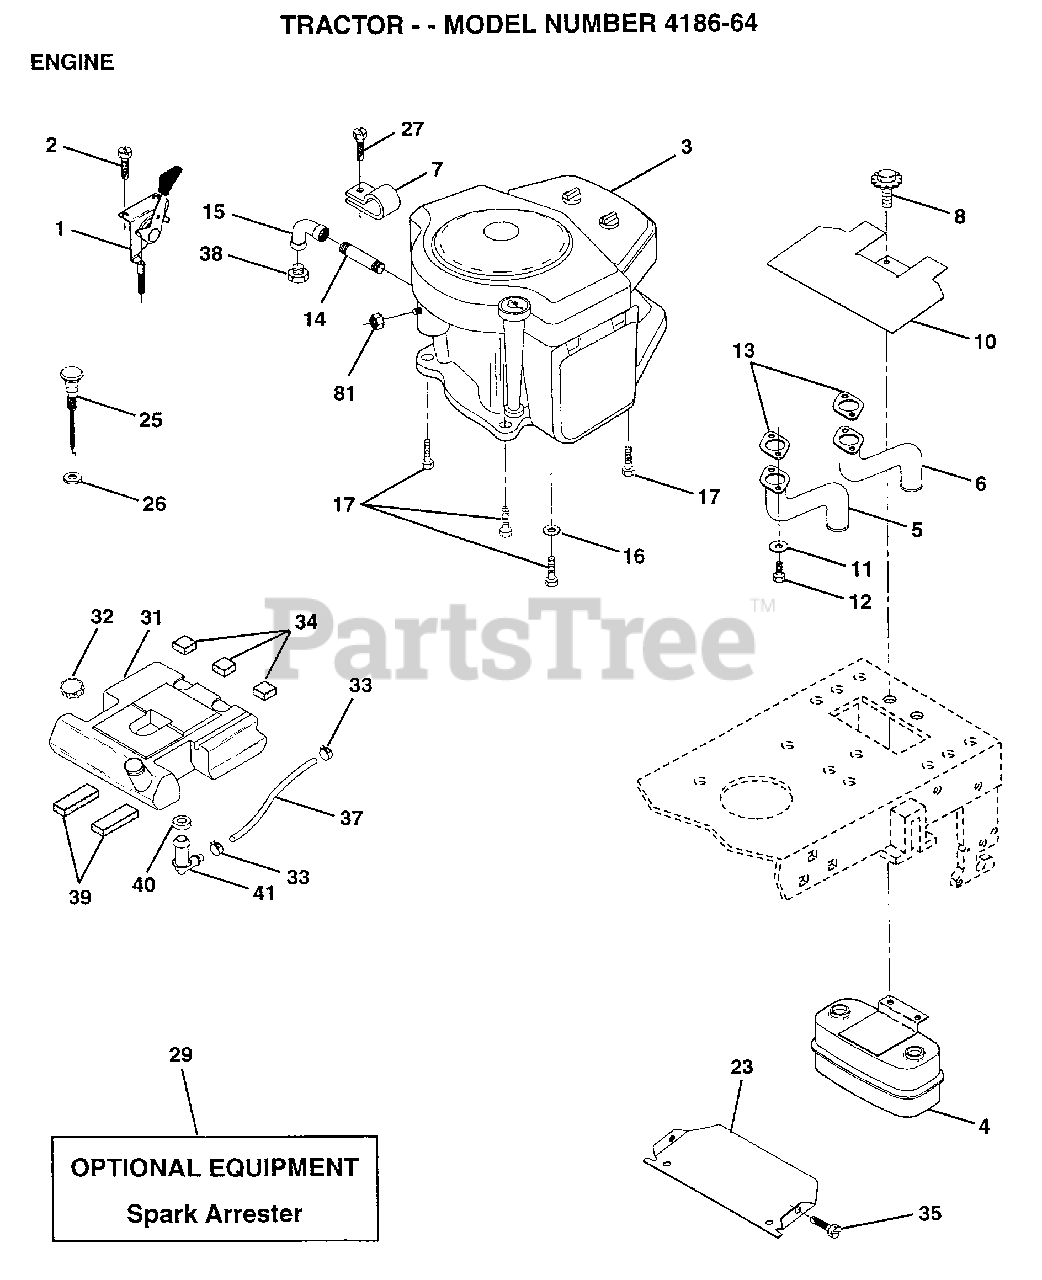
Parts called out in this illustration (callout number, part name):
2	SCREW LT
3	ENGINE, B&S
4	MUFFLER.TW.LOTONE
5	EXHAUST.B&S.18.LH
6	EXHAUST.B&S.18.RH
7	CLAMP.TUBE.DBL.EN
8	BOLT.5/16-18.UNC
10	SHIELD.HEAT.
11	LOCKWASHER
13	GASKET MUFFLER
14	PIPE NIPPLE LT
15	ELBOW
16	LOCKWASHER
17	SCREW LT
25	"CONTROL.CHOKE.51"""
26	"NUT,KEPS 3/8-24IM"
27	"SCREW-TT,10-32 FL"
31	TANK FUEL REAR
32	CAP ASM FUEL
33	HOSE CLAMP
34	PAD-SPACER LT
35	SCREW
37	FUEL LINE T
39	PAD IDLER TI
40	BUSHING OUTLET T
41	STEM.TANK.FUEL
81	NUT
